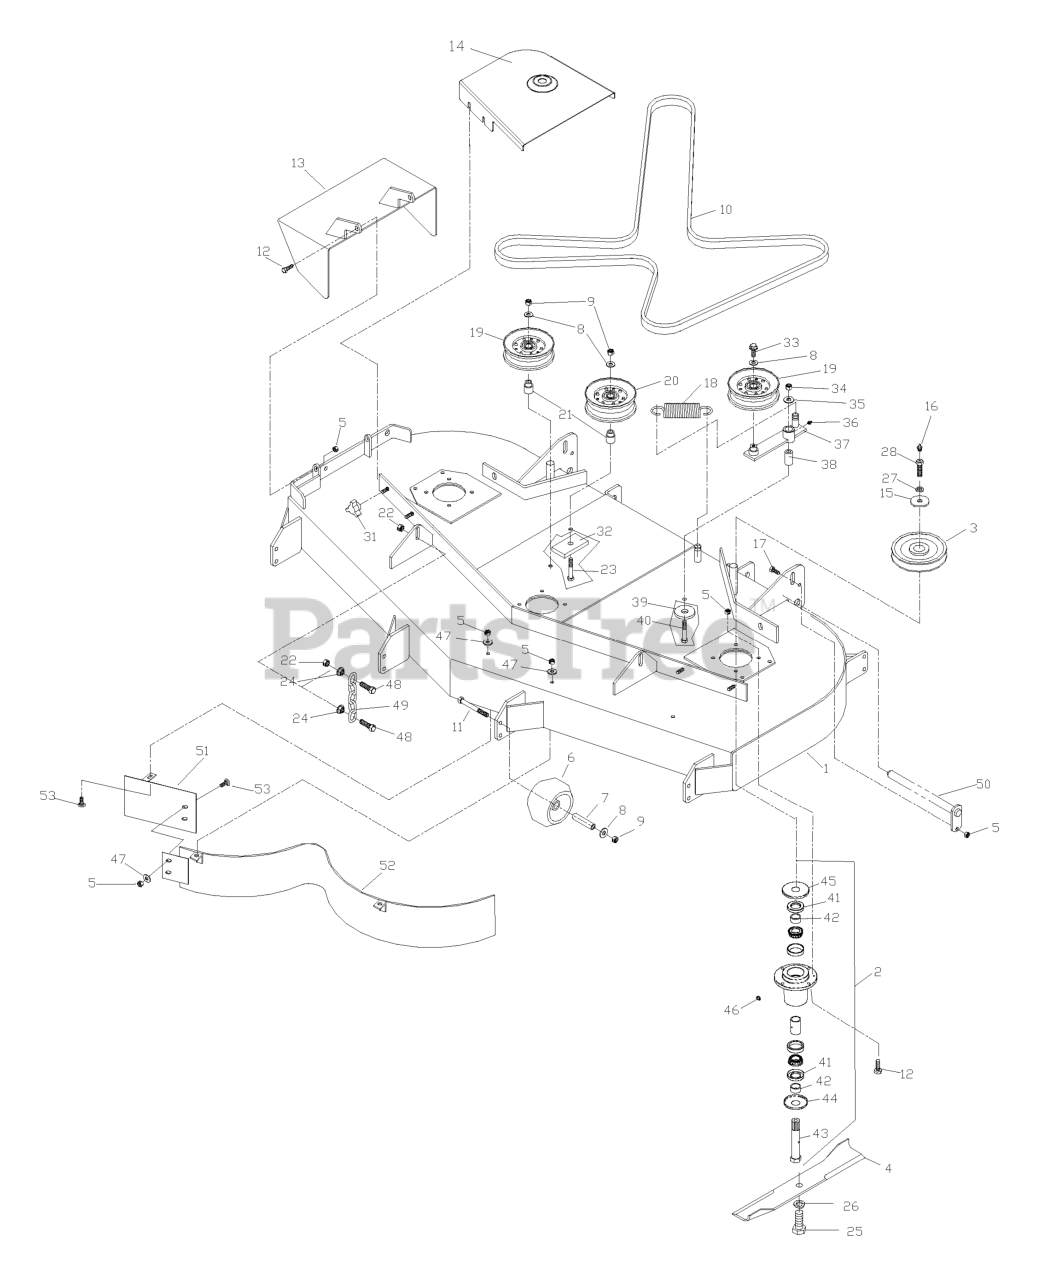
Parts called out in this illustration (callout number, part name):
1	DECK W/DECALS 52" HUS WSL
2	SPINDLE ASSY - 52/61"
3	PULLEY - 52"
4	BLADE OEM 18"
5	NUT 5/16C CENTERLOCK
6	ANTI-SCALP ROLLER
8	WASHER 3/8 FLAT
9	NUT 3/8C CENTERBLOCK
10	BELT, DECK
11	HCS 3/8C X 3 1/2
12	HCS 5/16C X 1 1/4
13	DISCHARGE CHUTE ORANGE
14	RT 52 SHIELD, ORANGE
15	SPINDLE WASHER
16	ZERK
17	HCS 5/16C X 3/4
18	DECK SPRING
19	IDLER PULLEY
20	IDLER PULLEY (TALL)
21	IDLER BUSHING
22	NUT 7/16C CENTERLOCK
23	HCS 3/8C X 2 1/2
24	NUT 7/16C WHIZ
25	HCS 5/8F X 1 1/4
26	LOCKWASHER 5/8
27	WASHER 7/16 LOCK
28	DRILLED BOLT 7/16-20 X 1 1/2"
31	KNOB, THREE PRONG
32	SUPPORT PLATE
33	4CS 3/8C X 1 SERRATED HEAD
34	NUT 1/2-13 HEX NYLOC ZD
35	WASHER 1/2 FLAT
36	ZERK
38	PIVOT BUSHING
39	WASHER, SUPPORT
40	HCS 1/2C X 3 1/4
41	SHAFT SEAL
43	52/61 SPINDLE - SPLINED SHAFT
44	BOTTOM DUST CAP
45	TOP DUST CAP
46	PLUG-VENTED
47	WASHER 5/16 FLAT
48	HCS 7/16C X 1 1/2
49	LIFT CHAIN
51	CENTER BAFFLE - 52"
52	MAIN BAFFLE 52"
53	CARRIAGE BOLT 5/16C X 5/8"
